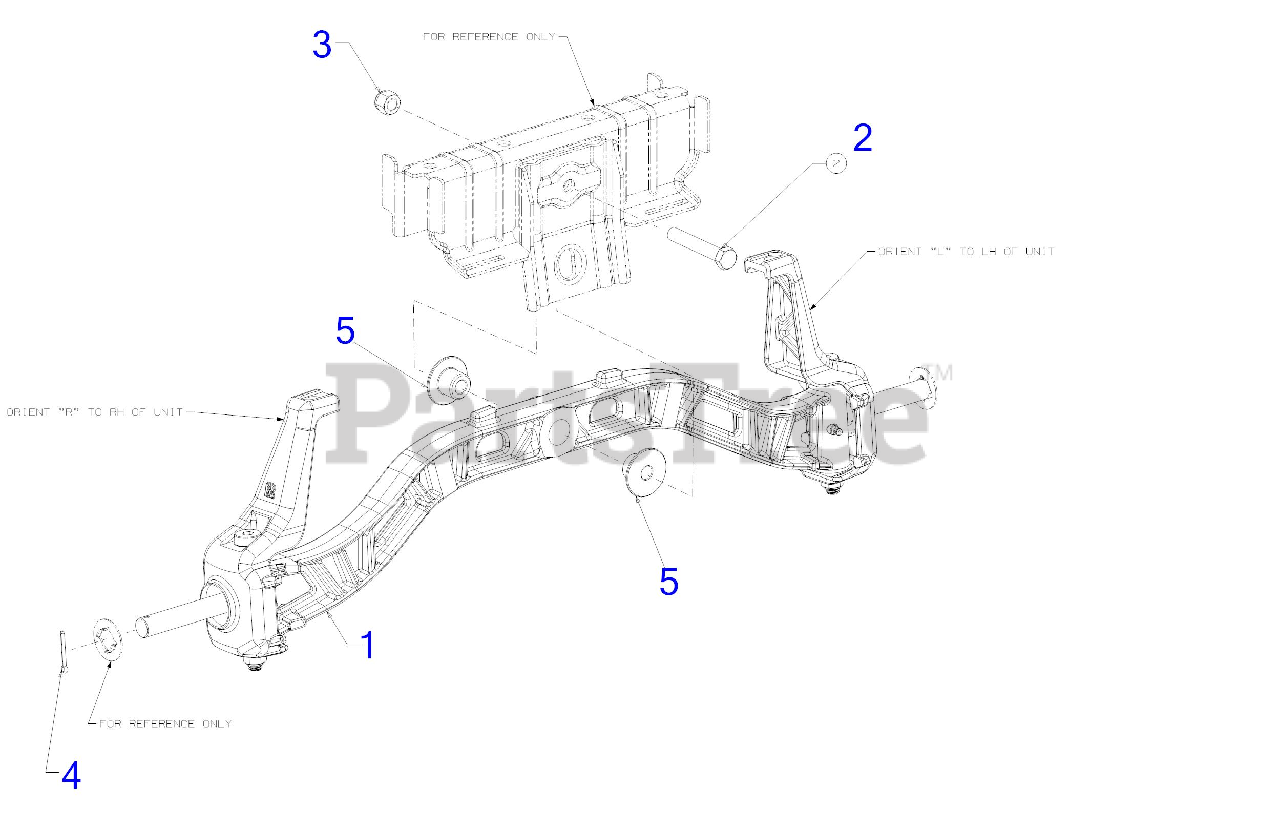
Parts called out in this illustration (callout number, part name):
1	FRONT AXLE ASSEMBLY
2	HEX SCREW 1/2-13 x 3.00
3	HEX LOCK NUT NYLON
4	COTTER PIN-5/32 DIA
5	SHOULDER SPACER
